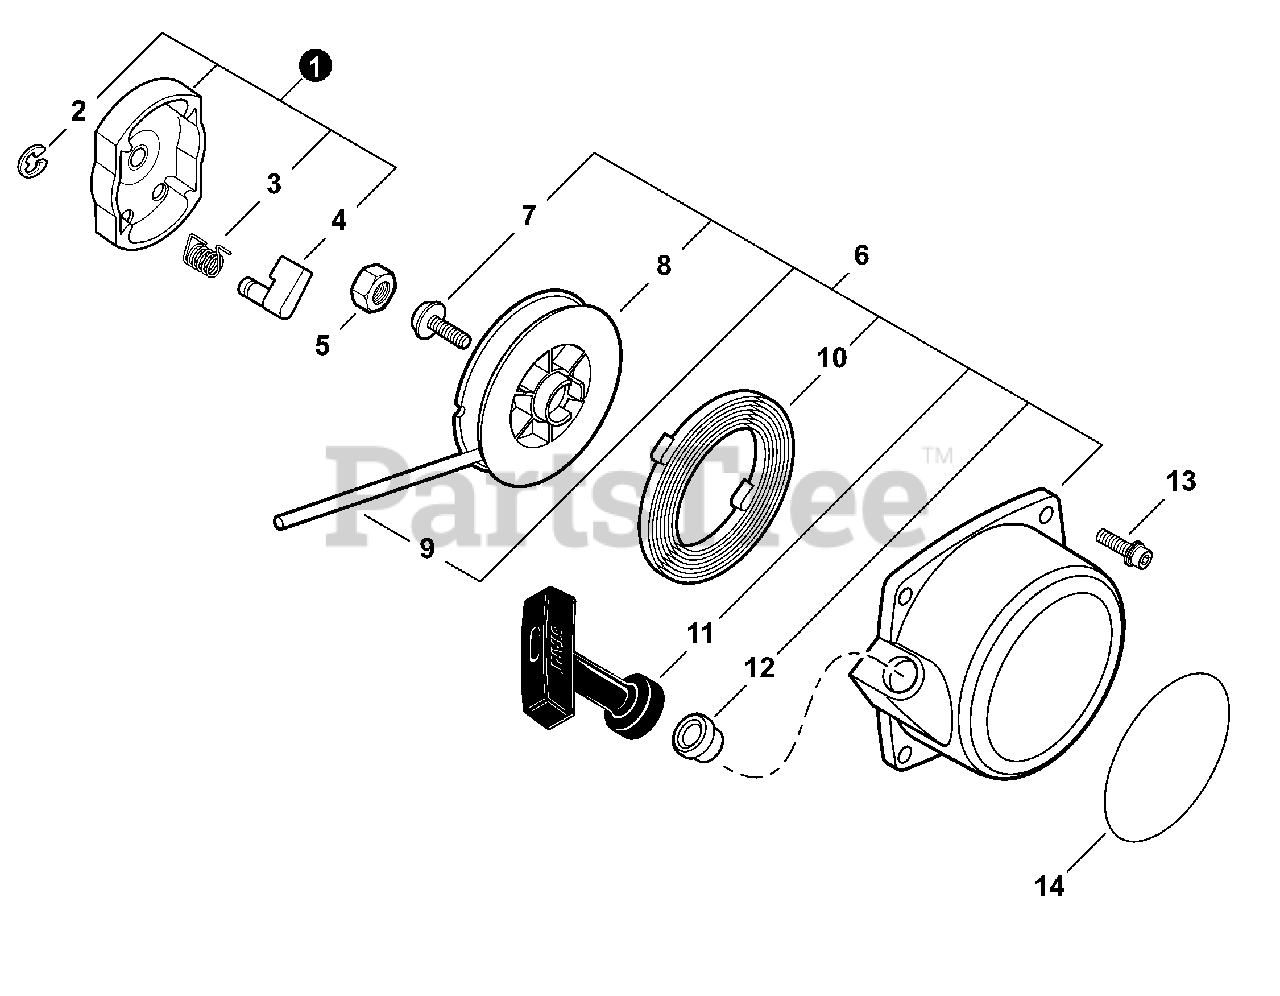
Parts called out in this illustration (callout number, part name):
1	PULLEY ASSY, STARTER
2	E-RING 4
3	SPRING, RETURN
4	PAWL, STARTER
5	NUT 8×1.25
6	STARTER ASSY, RECOIL
8	REEL, ROPE
9	ROPE, STARTER 3.8×1150
10	SPRING, RECOIL
11	GRIP, STARTER
12	CASE, STARTER
13	GUIDE, ROPE
14	BOLT 5×20
15	LABEL, STARTER - SHINDAIWA
